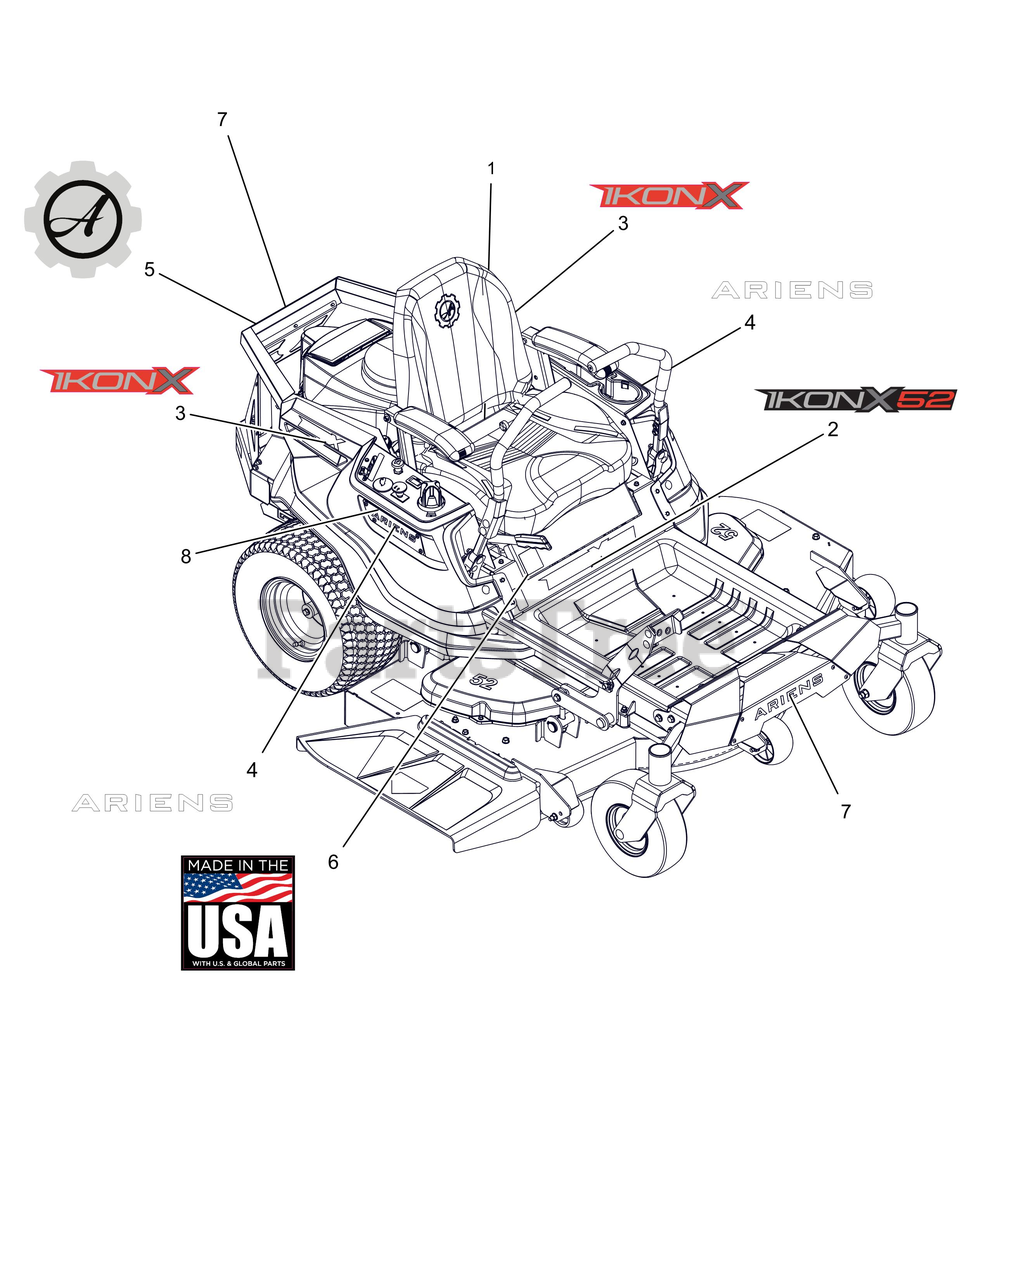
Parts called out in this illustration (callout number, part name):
1	DECAL, U1 BATTERY REPLACEMENT
2	DECAL, IKON-X 52"
3	DECAL, IKON
4	DECAL, ARIENS (6.50")
5	DECAL, ARIENS-GEAR BADGE
6	DECAL, MADE IN USA
7	DECAL - ARIENS 9.625"
8	DECAL, CUT HEIGHT - IKON CE
